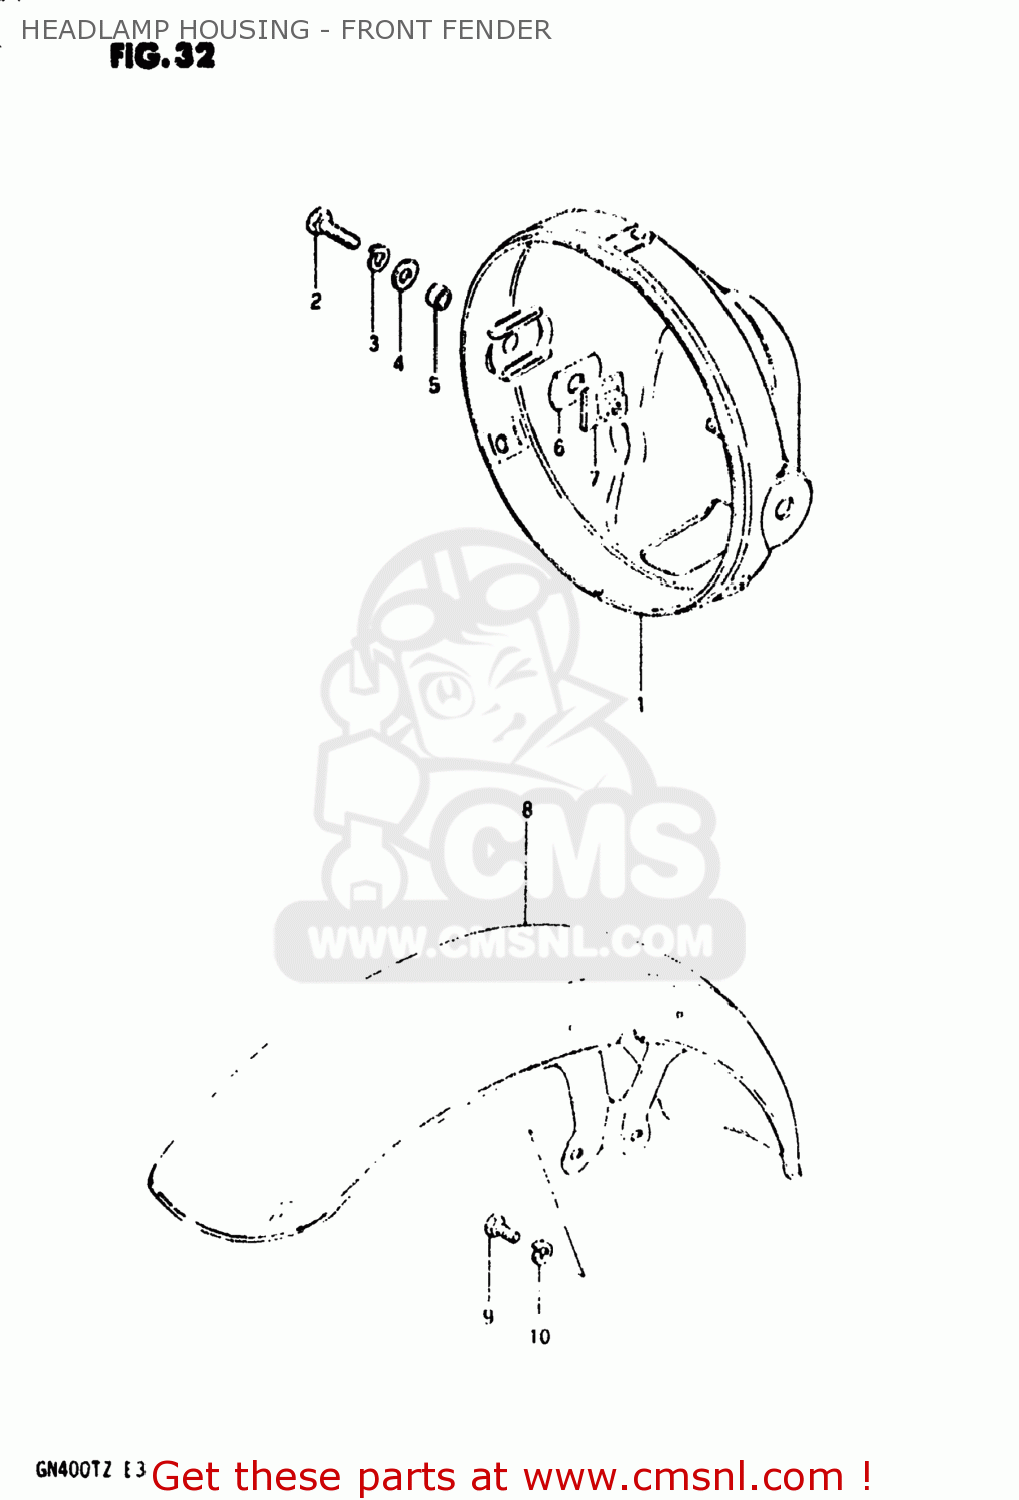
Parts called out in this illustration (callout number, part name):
1	HOUSING,HEADLAMP
2	BOLT
3	LOCK WASHER
4	WASHER
5	SPACER (8.8X12X7)
6	CUSHION
7	PLATE,HEADLAMP HOUSING
8	FENDER,FRONT
9	BOLT
10	LOCK WASHER
